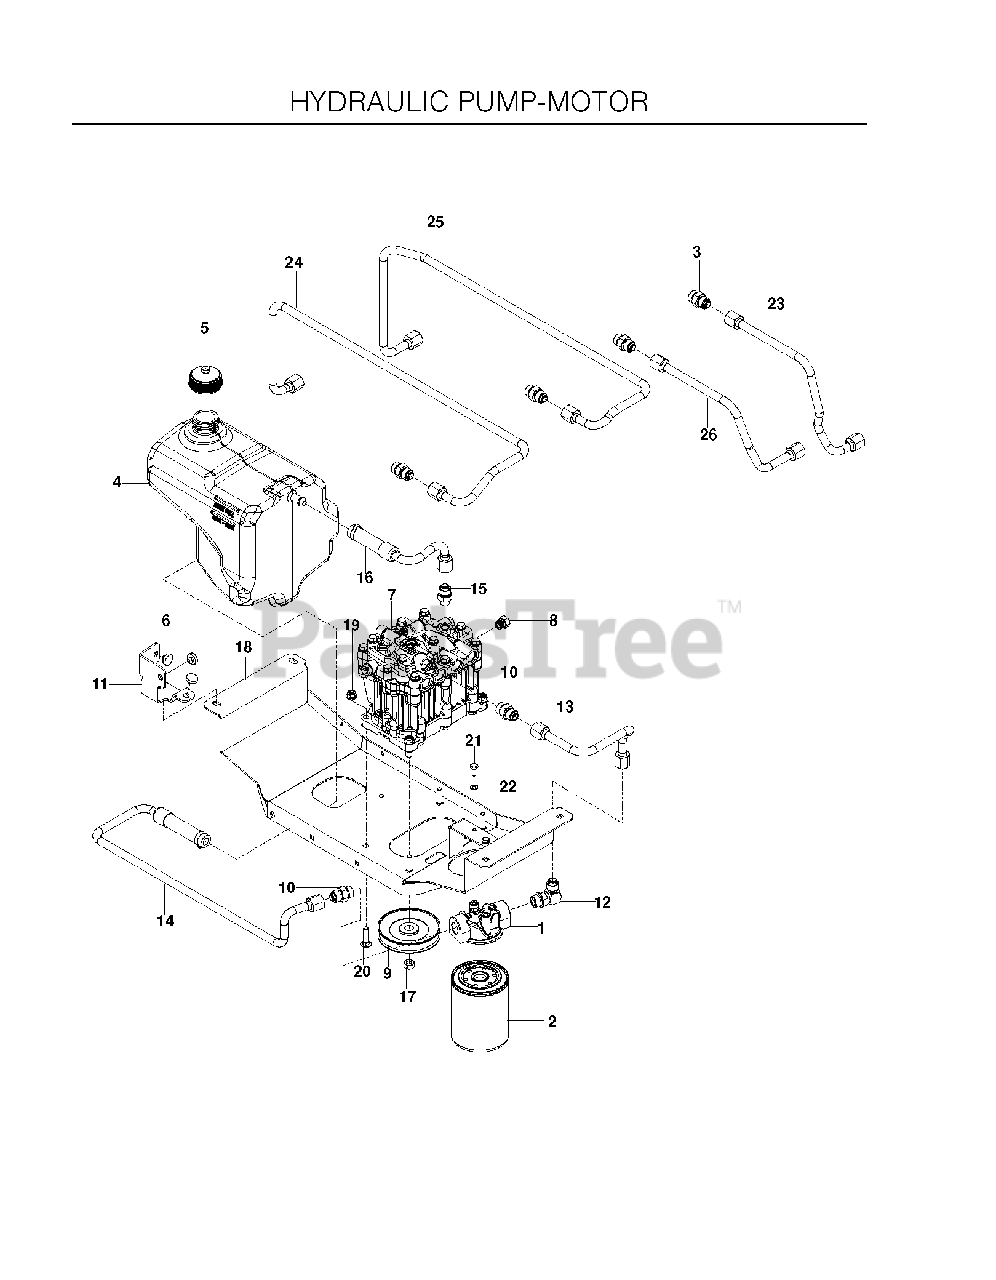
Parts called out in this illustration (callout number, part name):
1	FILTER HEAD
2	HYDRAULIC OIL FILTER
3	FITTING, STRAIGHT F6400-8-8-0
4	RESERVOIR HYDRO
5	HYDRAULIC CAP
6	GROMMET, BUMPER
7	PUMP, DUP10S (77808041201)
8	PLUG, 6408-6
9	PULLEY, PUMP
10	FITTING, 10-8 STRAIGHT
11	SUPPORT, RESERVOIR
12	FITTING, 10-8 90 DEG
13	HYD LINE, CHARGE
14	HYD LINE, INLET
15	FITTING, HYDRO
16	HYDRO LINE, CASE
17	NUT M10-1.5 L/H HEX
18	PLATE, PUMP
19	5/16-18 NYLOC FLANGE NUT
20	BOLT, CARRIAGE 5/16X1-1/4
21	HCS 1/4C X 5/8
22	LOCKWASHER 1/4"
23	HYDRO LINE, D
24	HYDRO LINE, A
25	HYDRO LINE, B
26	HYDRO LINE, C
